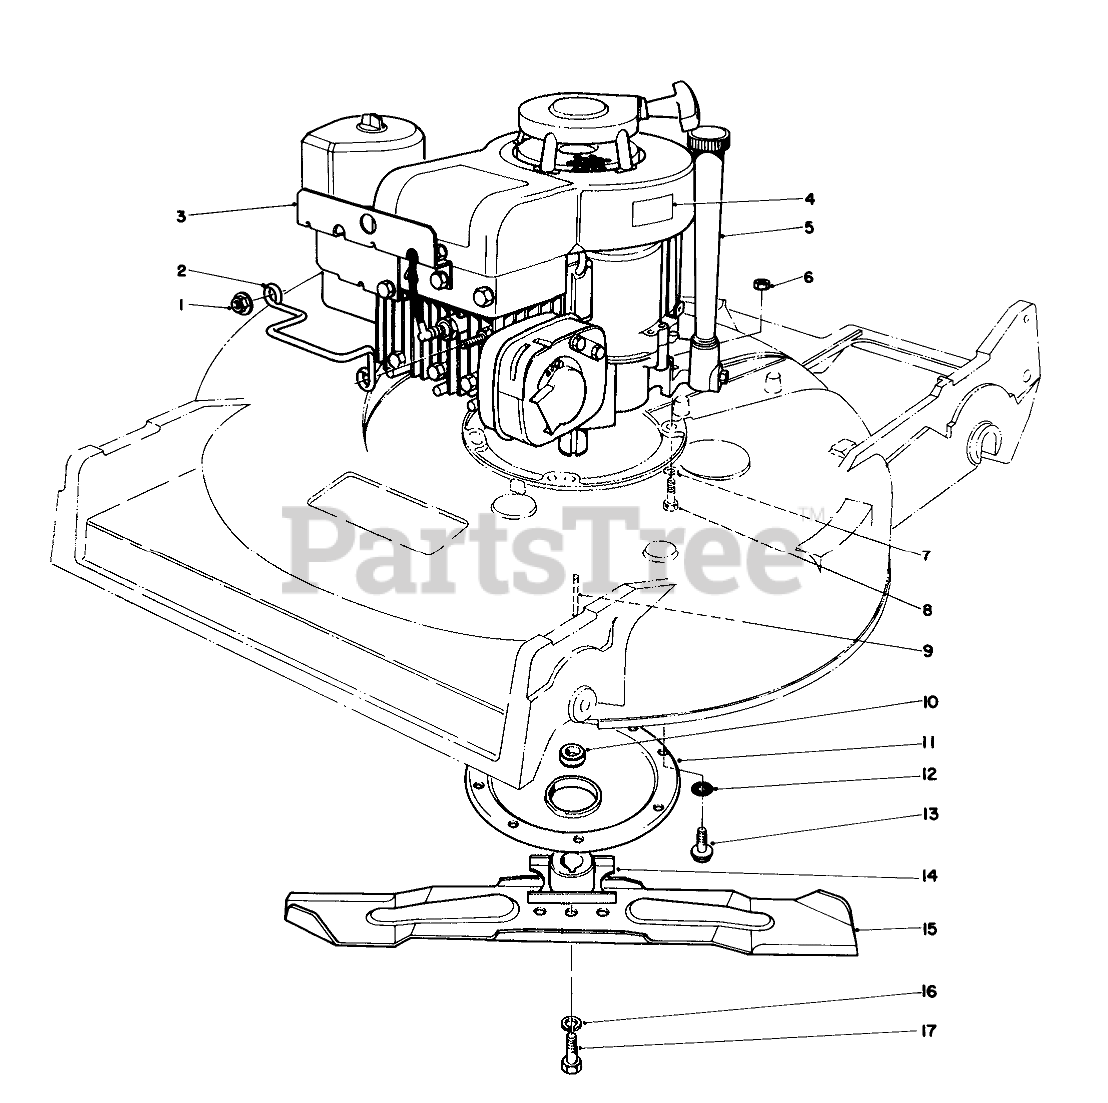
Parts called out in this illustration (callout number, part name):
1	NUT-HF
2	Protector-Spark Plug
3	ENGINE GD BRKT
4	Decal-Oil Caution
5	Engine
6	NUT-LOCK, CONE
7	WASHER-PLAIN
8	SCREW-HH
10	BLADE RETAINER SPACER
11	PROTECTOR-CRANKSHAFT
12	WASHER-LOCK, INTERNAL
13	SCREW-HWHTF
14	BLADE RETAINER W A
15	BLADE-21in
16	WASHER-LOCK
17	BLADE SCREW
